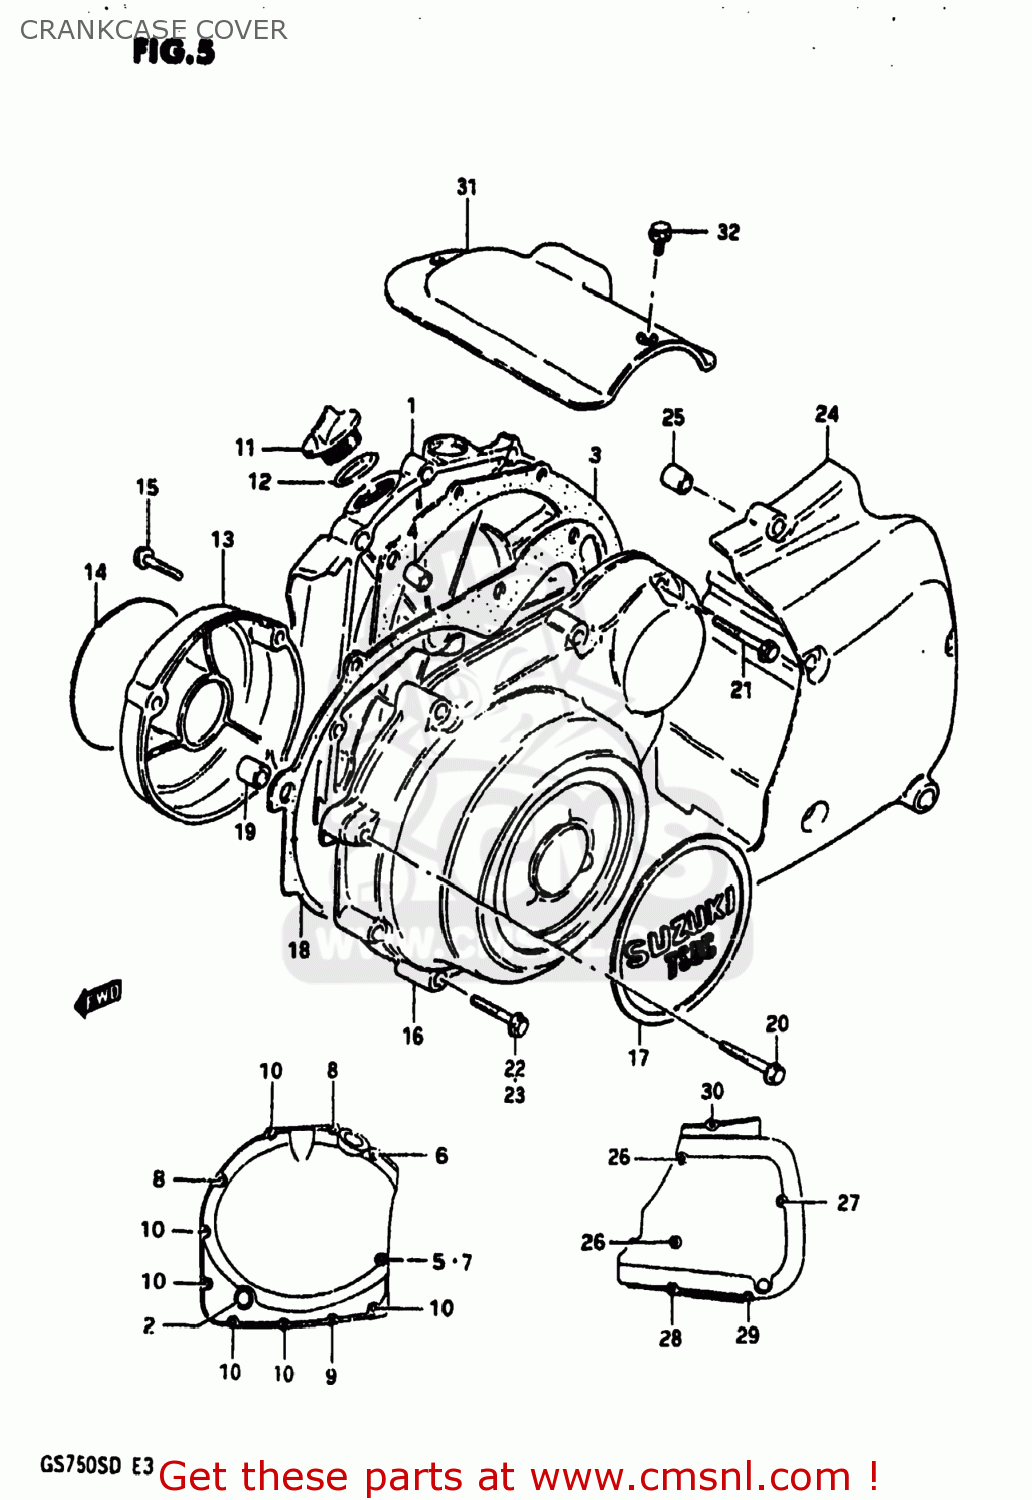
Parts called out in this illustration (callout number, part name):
1	COVER,CLUTCH
2	LENS,OIL LEVEL CHECK
3	GASKET,CLUTCH COVER (MCA)
4	PIN
5	WASHER
6	BOLT (6X40)
7	BOLT (6X35)
8	BOLT (6*30)
9	BOLT (6X25)
10	BOLT 6X20
11	CAP
12	O RING(D:2.2,ID:32)
13	COVER,CONTACT BREAKER
14	EMBLEM
15	BOLT (5X30)
16	COVER
17	EMBLEM,MAGNETO COVER
18	GASKET,MAGNETO COVER (MCA)
19	PIN
20	BOLT (6X45)
21	BOLT (6X40)
22	BOLT (6X35)
23	BOLT (6*30)
24	COVER,ENGINE SPROCKET
25	PIN
26	BOLT (6X95)
27	BOLT (6X85)
28	BOLT (6X70)
29	BOLT (6X55)
30	BOLT (6*30)
31	COVER,STARTER MOTOR
32	BOLT (5X8)
